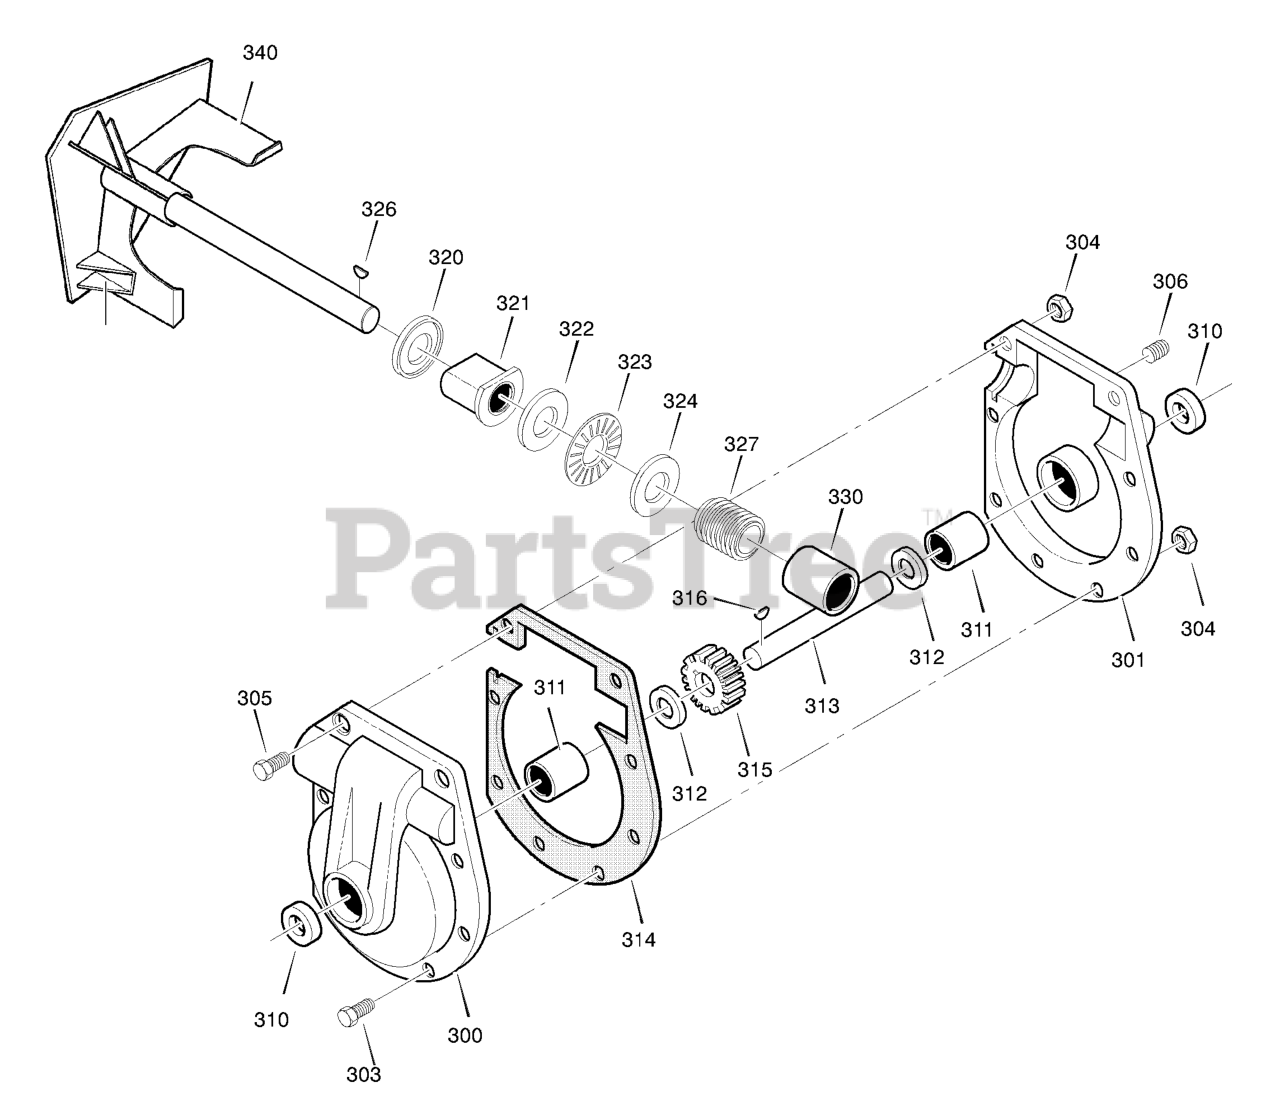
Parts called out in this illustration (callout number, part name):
300	CASE, GEAR, RH
301	CASE, GEAR, LH
303	SCREW,1/4-20X.75
304	NUT,1/4-20
305	NUT, 1/4-20 HEXKEPS
306	SCREW, 3/8-16 x 0.50
310	SEAL, OIL
311	BEARING, FL
312	WASHER, FLAT
313	SHAFT, AUGER OUTPUT
314	GASKET, GEAR BOX
315	WORM GEAR
316	KEY, WOODRUFF #61
320	BRNG, FL
321	SHAFT, AUGER INPUT
322	COLLAR, THRUST
323	PIN, SPRING
324	WASHER, FLAT
326	BRNG, FL
327	SEAL, OIL
330	BEARING
340	IMPELLER
